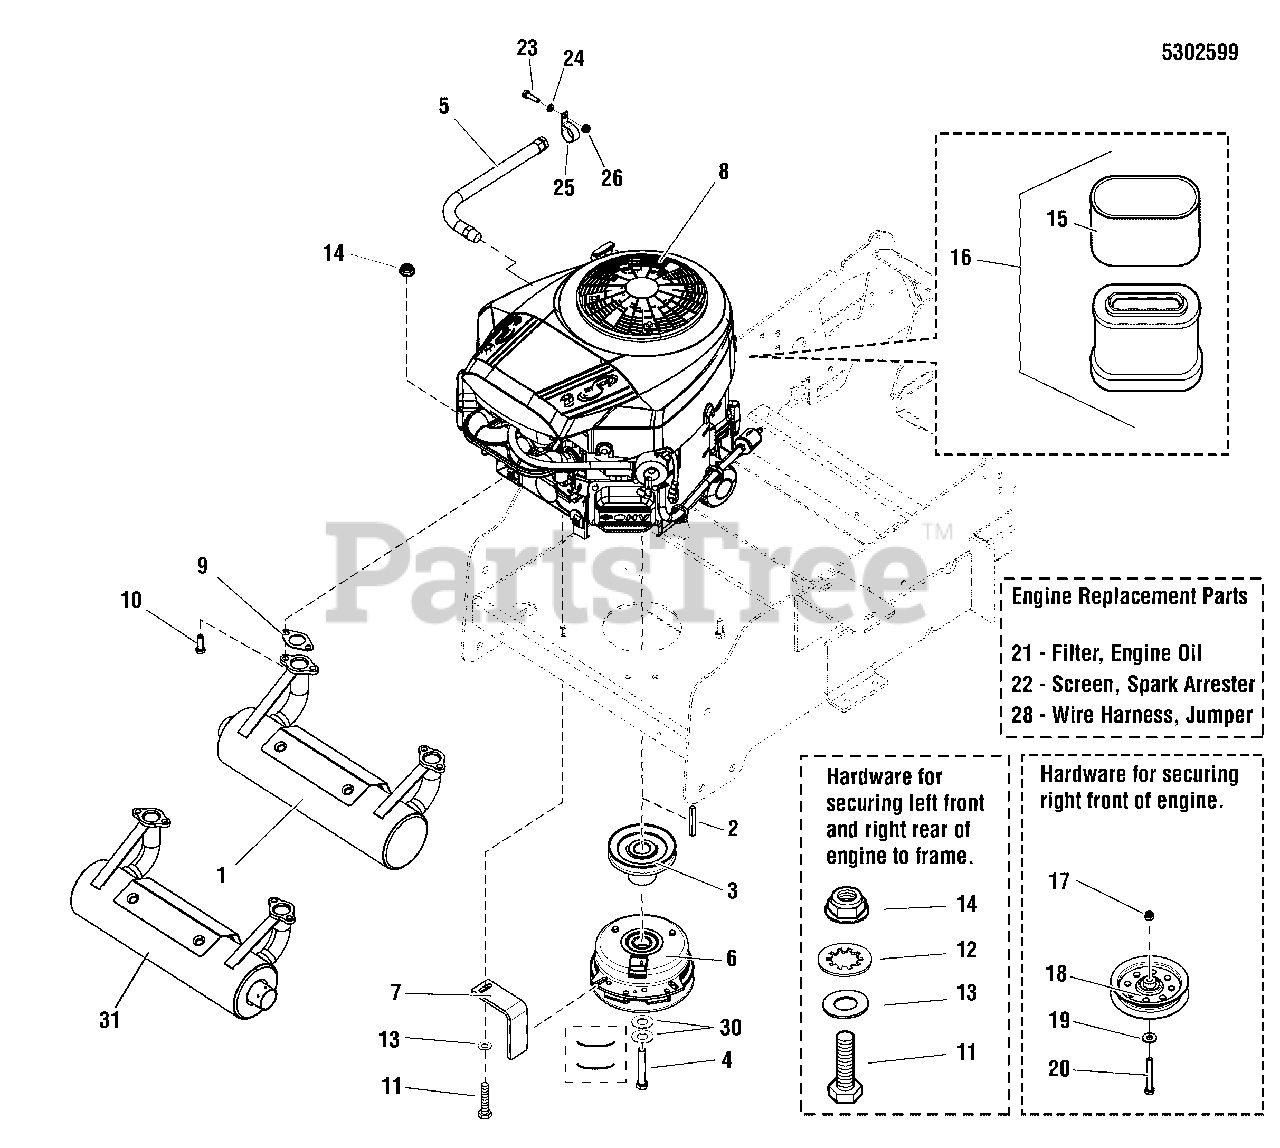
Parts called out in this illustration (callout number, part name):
1	MUFFLER, B&S-ELS
2	KEY, 1/4 SQ. X 1.00
3	PULLEY, PUMP DRIVE, 4.857 OB X 1" BORE
5	HOSE, OIL DRAIN
6	CLUTCH, # 5219-34A, ELECTRIC, IS500Z
7	ANCHOR, CLUTCH - BLK
8	ENGINE, B&S
11	BOLT, 5/16-18 X 1-3/4 GD5 YZ
12	WASHER, 5/16" INT. TOOTH LOCK
13	WASHER, 5/16" SAE
14	NUT, 5/16-18 HEX NYLON LOCK
15	PRE CLEANER (SV)
16	AIR CLEANER W/ PRE CLEANER (SV)
17	SEE PUMP DRIVE GROUP
18	SEE PUMP DRIVE GROUP
19	SEE PUMP DRIVE GROUP
20	SEE PUMP DRIVE GROUP
23	BOLT, 1/4-20 X 1" GD5 CZ
24	WASHER, 1/4 SAE (5025154)
25	CLAMP, VINYL INSULATED
26	NUT, 1/4-20 HEX NYLOCK FLANGE (5025391)
30	BELLEVILLE WASHER 1.1875 X .442 X .089
31	MUFFLER, RIGHT OUTLET ASSY
